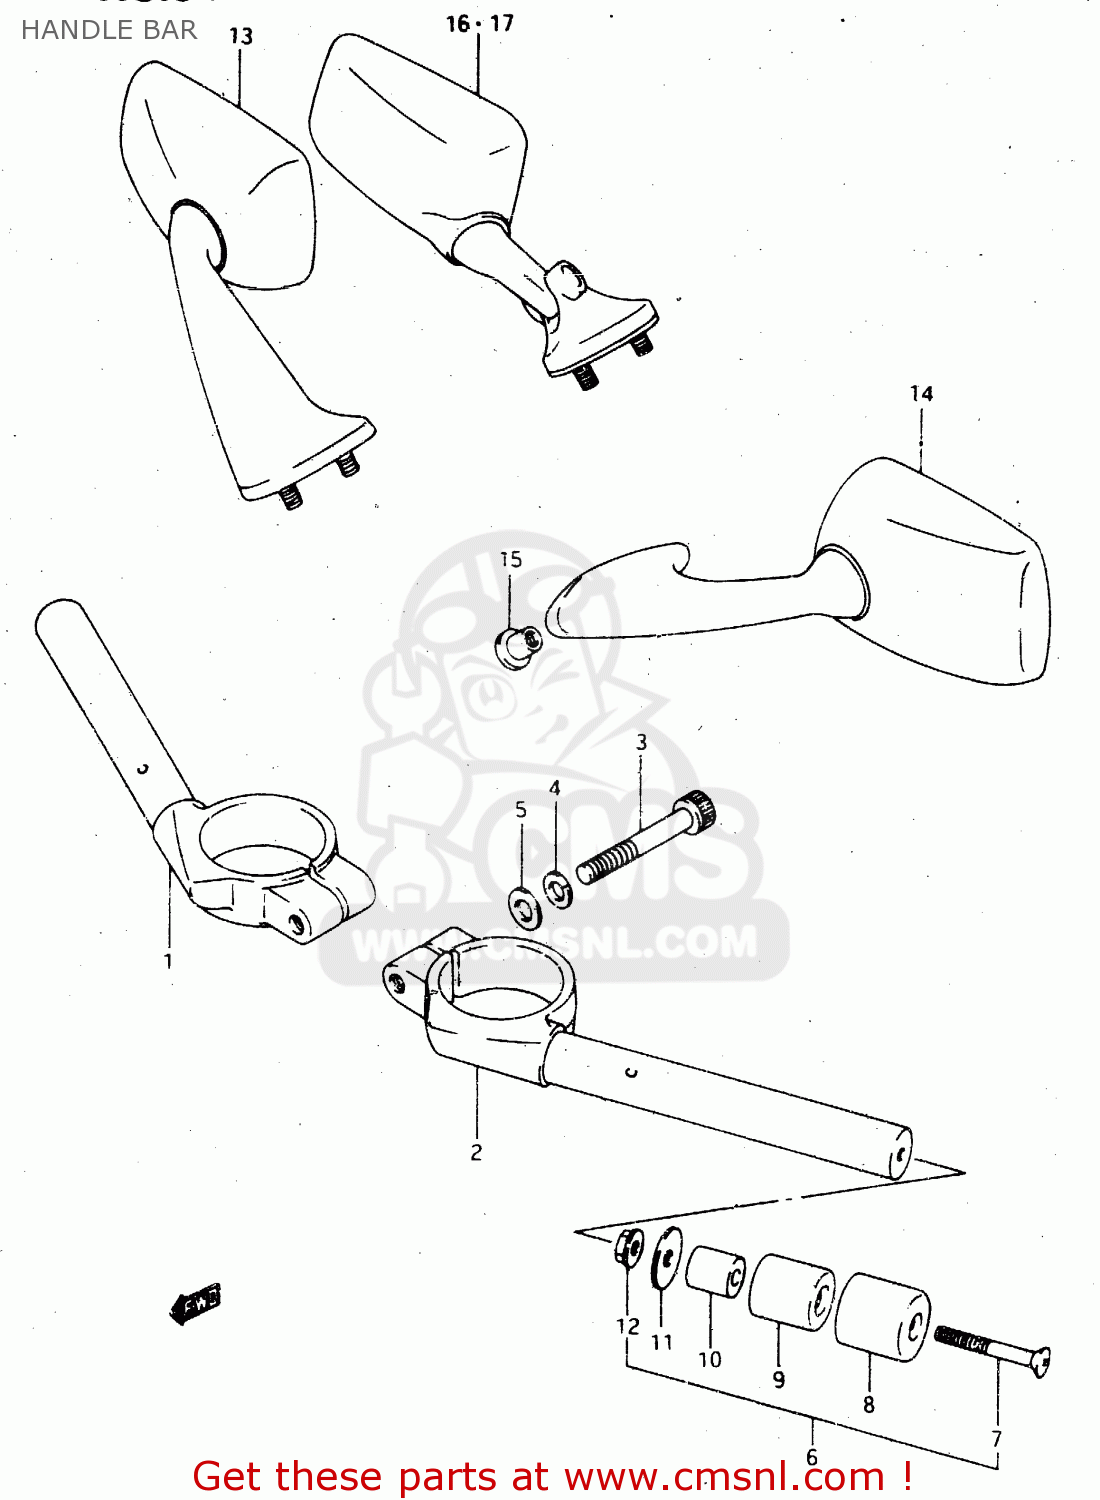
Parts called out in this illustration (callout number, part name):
1	HANDLEBAR,R
2	HANDLEBAR,L
3	BOLT
4	WASHER,LOCK
5	WASHER
6	BALANCER SET,HANDLEBAR
7	SCREW
8	CAP,BALANCER
9	BALANCER,HANDLE
10	EXPANDER,HANDLE BALANCER
11	SPACER,BALANCER
12	NUT
13	MIRROR ASSY R.
14	MIRROR, L.
15	NUT,RR VIEW MIRROR
16	MIRROR ASSY,RR VIEW,R
17	MIRROR ASSY,RR VIEW,L
